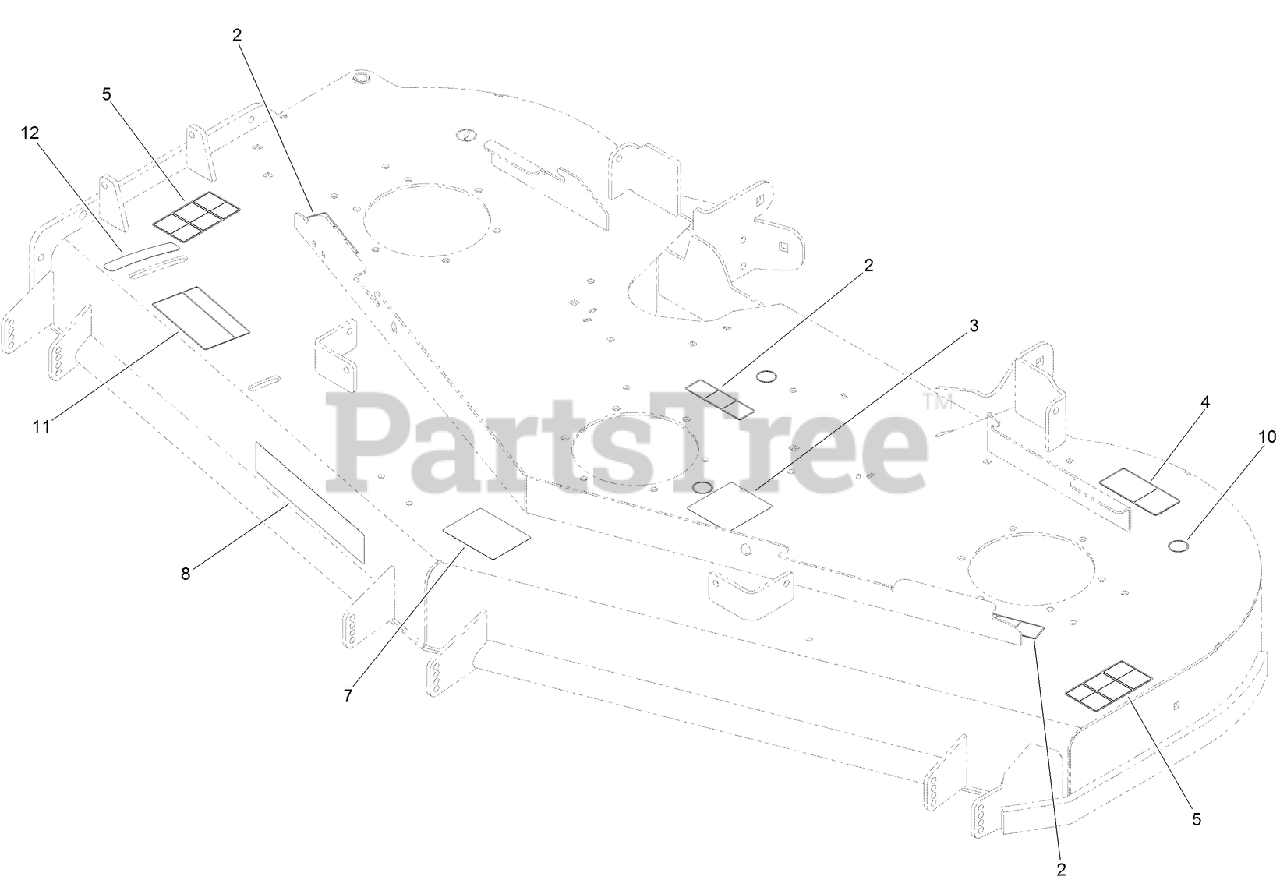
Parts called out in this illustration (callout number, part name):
2	DECAL-MISSING, COVER
3	DECAL-ROUTING, DECK BELT
4	DECAL-TORQUE, BLADE BOLT
5	DECAL-DANGER
7	DECAL-SCALP, ANTI
10	DECAL-GREASE
11	DECAL-ADJUSTMENT, BAFFLE
12	DECAL-SETTING, BAFFLE
